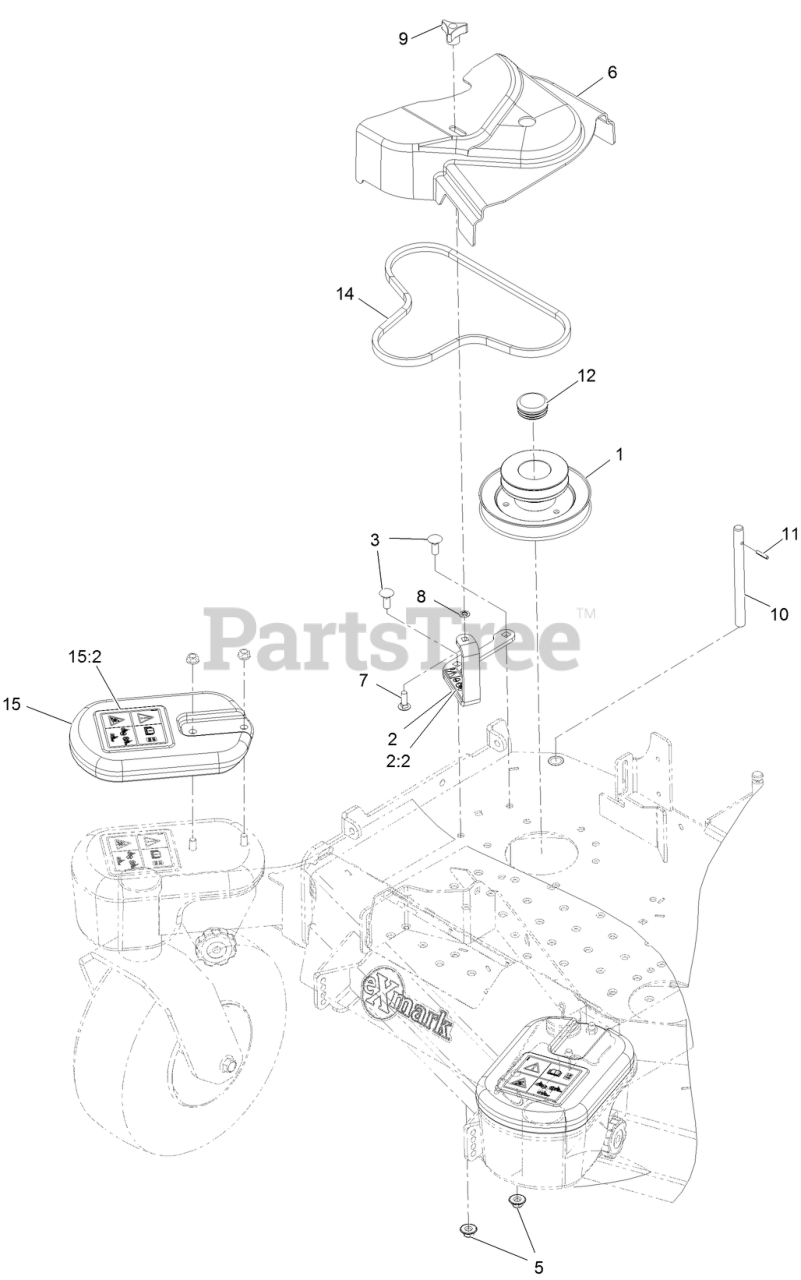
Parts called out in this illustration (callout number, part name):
1	JACKSHAFT- UV DRIVE 483
2	ASM-CVR BRKT W/DECAL
2:2	DECAL-DANGER
3	BOLT-CARR
5	Nut-Nyloc 3/8-16 Flg
6	COVER-BELT, UV 48
7	BOLT-CARR
8	RING-RETAINING, BOLT
9	KNOB-3 PRONG
10	SHAFT-CATCHER, GRASS
11	PIN-ROLL
12	PLUG-ROUND PLASTIC
14	BELT-BLOWER
15:2	DECAL-WARNING, TRACTION
